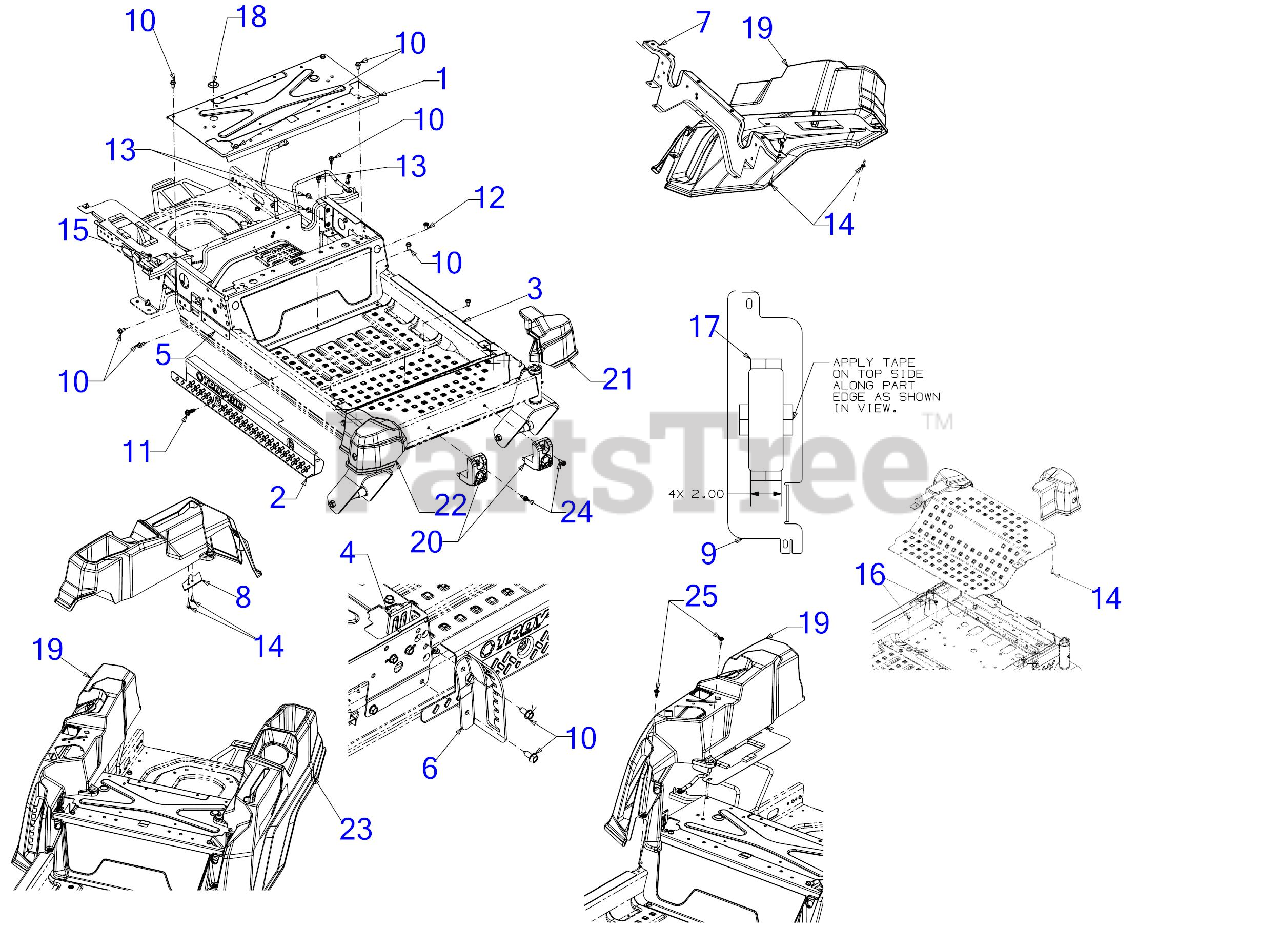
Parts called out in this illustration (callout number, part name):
6	HEIGHT INDEX BRACKET
10	SCREW 5/16-18 x .750
11	SCREW 3/8-16 x 1
12	SCREW 5/16-18 x .750
13	SCREW 5/16-18 x .500
14	SCREW 1/4-10 x .750
15	SCREW 1/4-20 x .750
16	SCREW 1/4-20X.625
17	FOAM TAPE .625 WIDE x .25 THK BULK
19	CONSOLE-RH
20	AXLE BUMPER
21	AXLE COVER (LH) W/O HEADLIGHT
22	AXLE COVER (RH) W/O HEADLIGHT
23	MANUAL PTO CONSOLE (LH)
24	SHOULDER SCREW 5/16-18X.75
25	SHOULDER SCREW M6-1 .368 X.115
